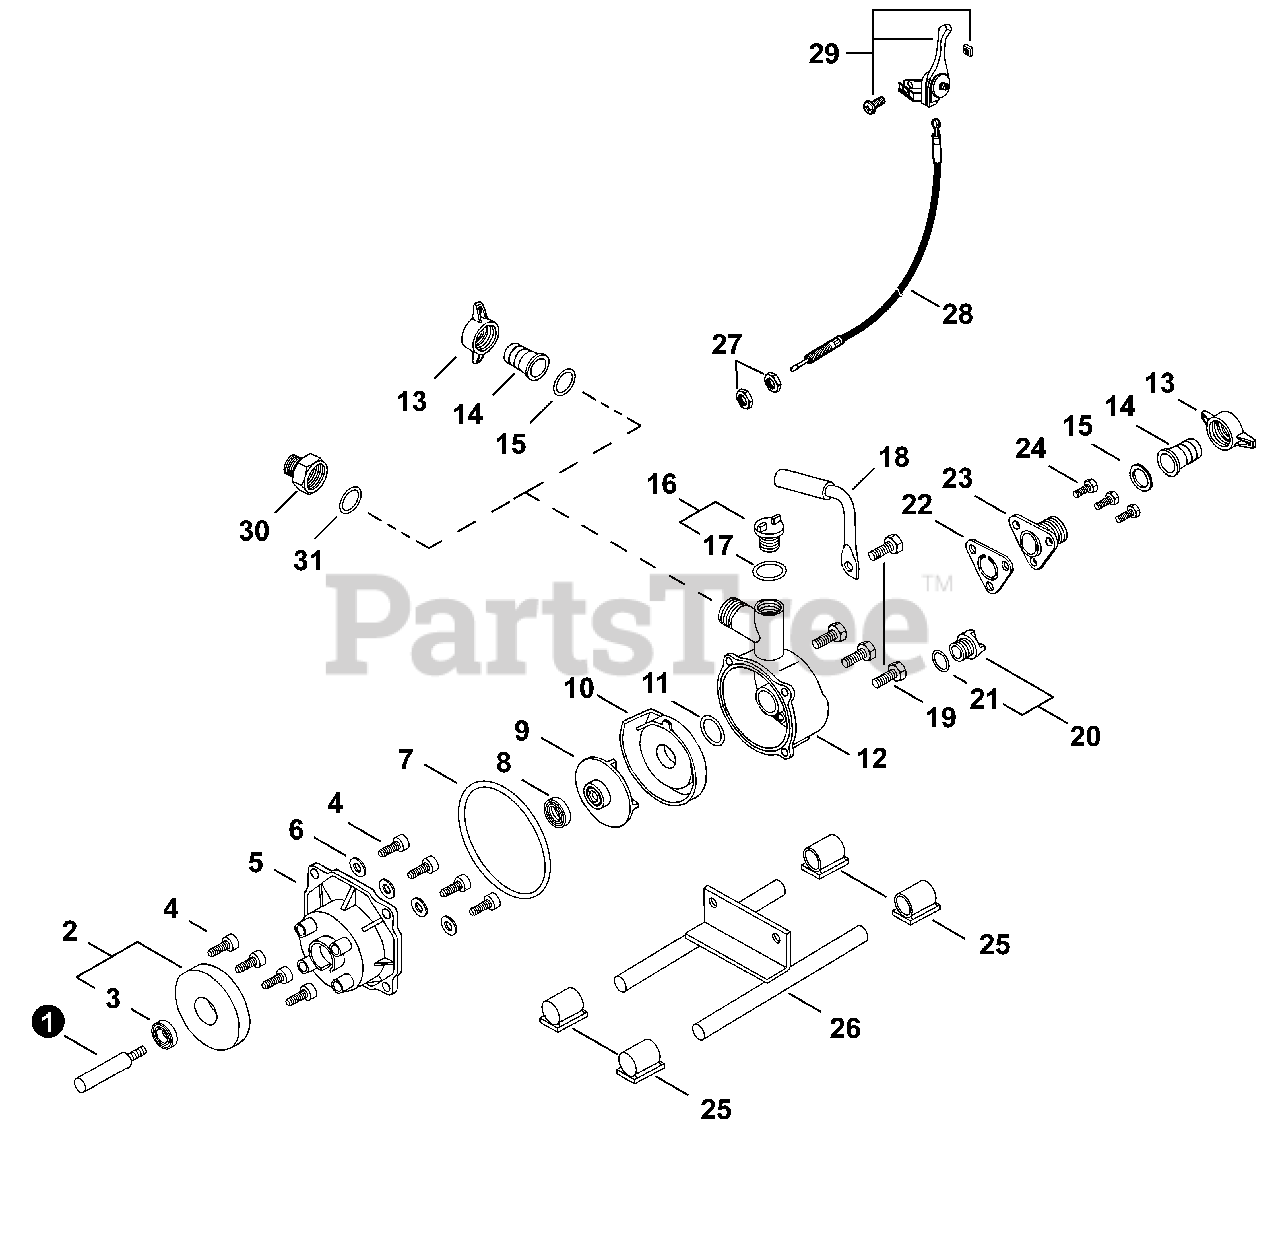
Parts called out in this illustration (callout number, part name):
1	SHAFT, PUMP
2	PUMP ADAPTOR ASSY
3	BEARING, BALL 6201
4	BOLT 5×25
5	CASE, PUMP
8	SEAL, MECHANICAL
9	IMPELLER
10	CASE, IMPELLER
12	CASE, PUMP
13	NUT, HOSE
14	COUPLING, HOSE
16	PLUG
19	BOLT TAPPING 8×35
20	PLUG
21	O-RING P-24
22	VALVE, CHECK
23	CASE, CHECK VALVE
24	BOLT - 6×20
26	FRAME, PUMP
28	CABLE, THROTTLE
29	CONTROL, THROTTLE
30	NIPPLE - 1×3/4"
